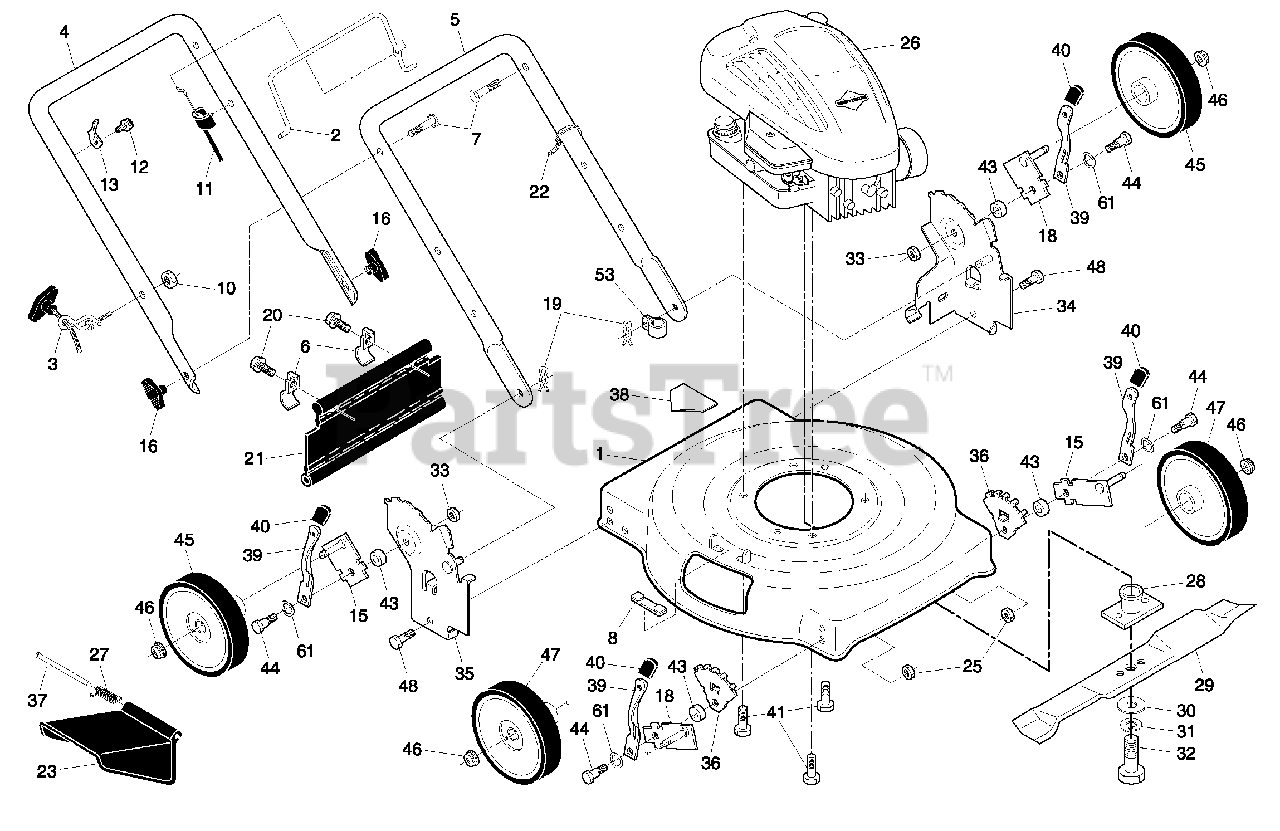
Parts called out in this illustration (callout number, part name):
1	Kit, Housing
2	Control Bar
3	Rope Guide
4	Upper Handle
5	Lower Handle
6	Shoulder Bolt 5/16-18 x 1/2
7	Handle Bolt 5/16-18
8	Clip, Closeout
10	Locknut, Hex 1/4-20
11	Engine Zone Control Cable
12	Screw, Hex Head, Threaded, Rolled #10-24 x 1/2
13	Up-Stop Bracket
15	Axle Arm Assembly, Left Front & Right Rear
16	Handle Knob
18	Axle Arm Assembly, Right Front & Left Rear
19	Hairpin Cotter
20	Screw, Tapping, Hex Washer Head #10-24
21	Rear Defl ector
22	Wire Tie
23	Discharge Guard
25	Nut, Hex, Flangelock 5/16-18
27	Torsion Spring
28	Blade Adapter
29	22" Blade
30	Hardened Washer
31	Helical Lockwasher 3/8
32	Screw, Hex Head, Grade 8, 3/8-24 x 1-3/8
33	Nut, Hex, Flangelock 5/16-18
34	Wheel Bracket Support (Left)
35	Wheel Bracket Support (Right)
36	Wheel Bracket Adjuster
37	Hinge Rod
38	Danger Decal
39	Selector Spring
40	Selector Knob
41	Screw, Hex Head, Threaded, Rolled 3/8-16 x 1
43	Spacer
44	Shoulder Bolt 5/16-18 x .33
45	Wheel & Tire Assembly, Rear
46	Nut, Hex, Flangelock 3/8-16
47	Wheel & Tire Assembly, Front
48	Screw, Hex Head, Serrated, Type TT 1/4-20
53	Clip, Cable
61	Washer, Curved, Cylindrical
61	Operator's Manual, English
61	Operator's Manual, French
61	Replacement Parts Manual, English / French
